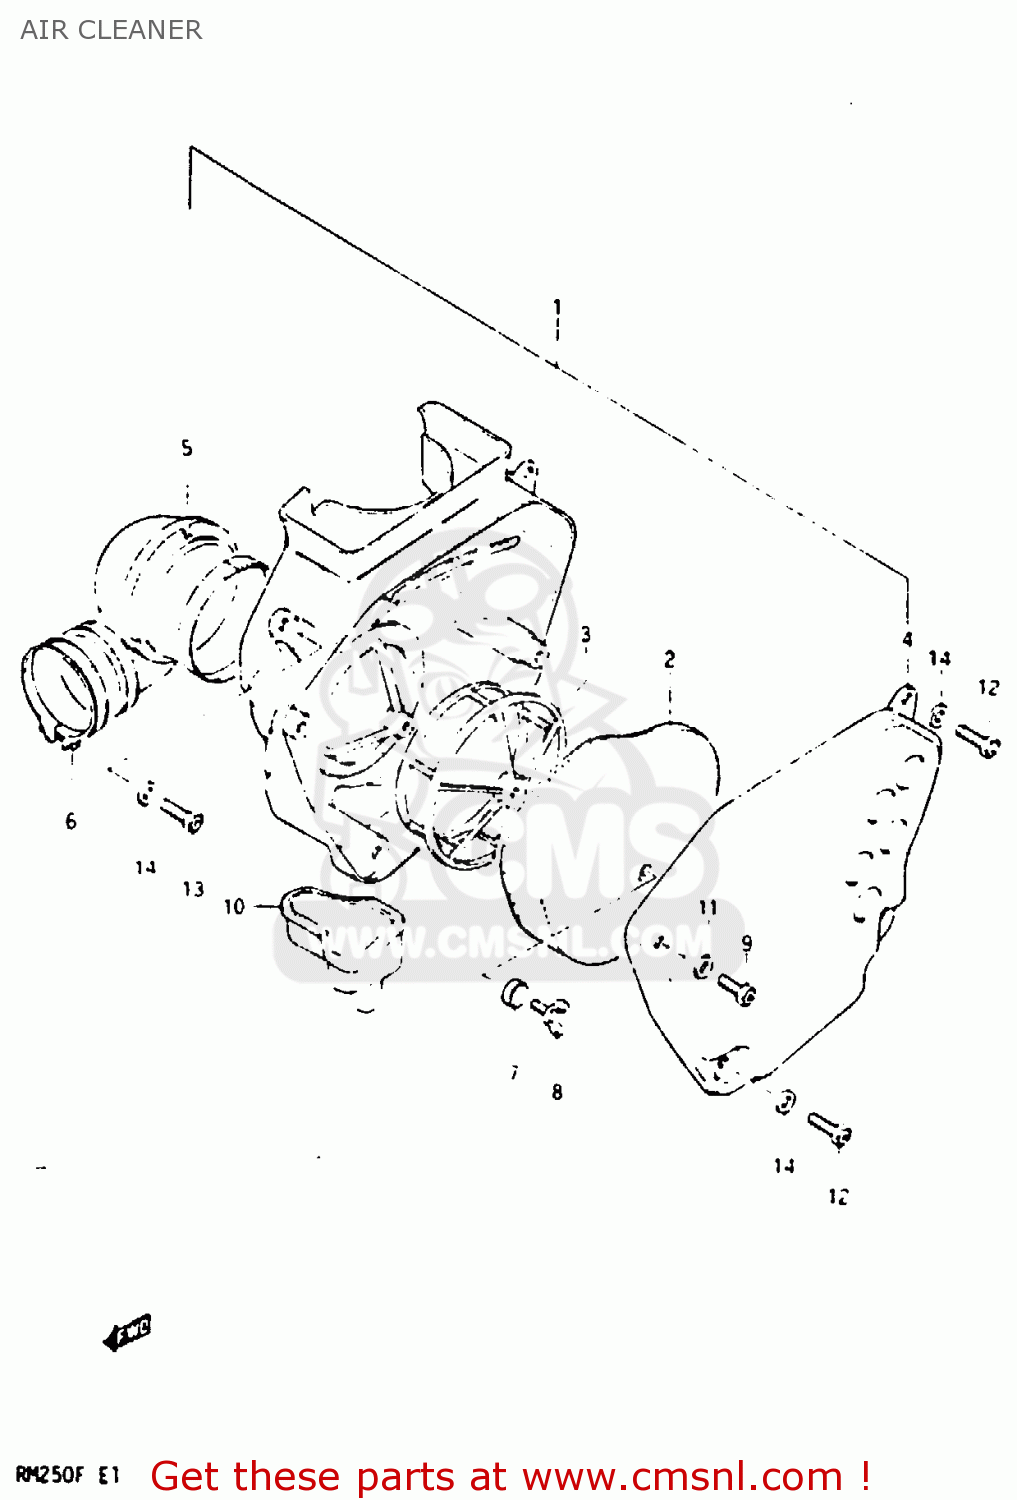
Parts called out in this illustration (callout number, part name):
1	CLEANER ASSEMBLY,AIR
2	FILTER,AIR CLEANER
3	HOLDER,FILTER
4	CAP,AIR CLEANER
5	TUBE,AIR CLEANER OUTLET
6	CLAMP
7	WASHER,FILTER HOLDER
8	BOLT,AIR CLEANER
9	SCREW
10	DRAIN TUBE
11	WASHER
12	SCREW
13	SCREW
14	WASHER
